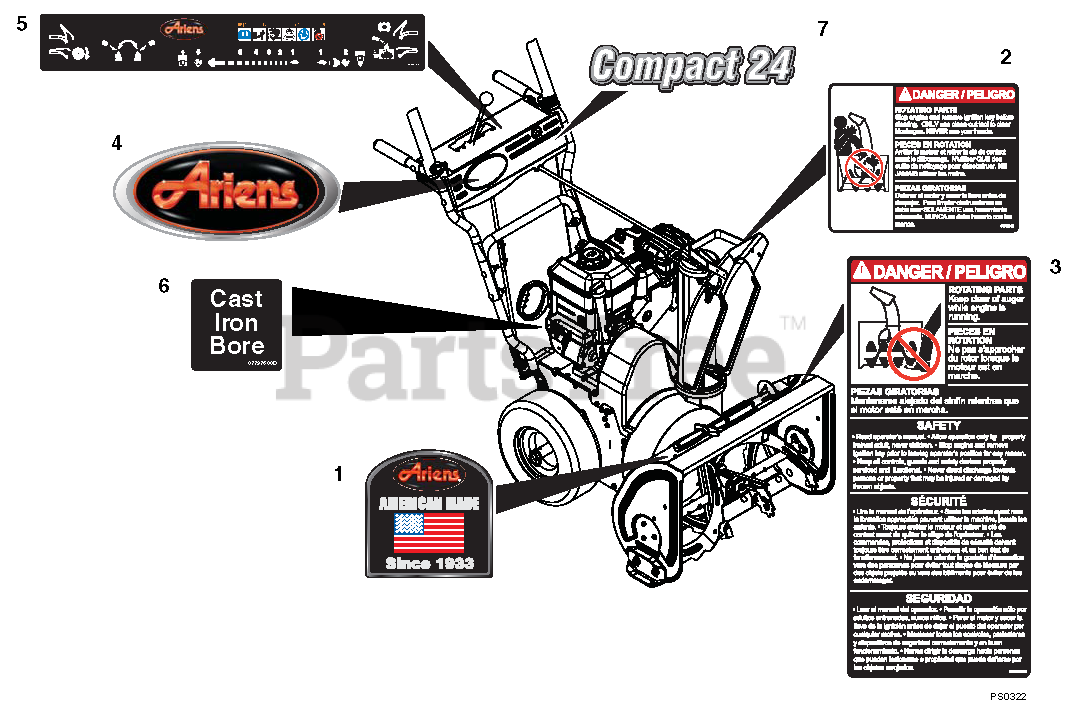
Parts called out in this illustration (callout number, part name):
1	DECAL, ARIENS SINCE 1933
2	DECAL, DANGER - ROT. PARTS
3	DECAL, DANGER
4	DECAL, ARIENS JEWEL
5	DECAL, CONTROL, COMPACT/DELUXE
6	DECAL - CAST IRON BORE
7	DECAL, ST20 COMPACT
